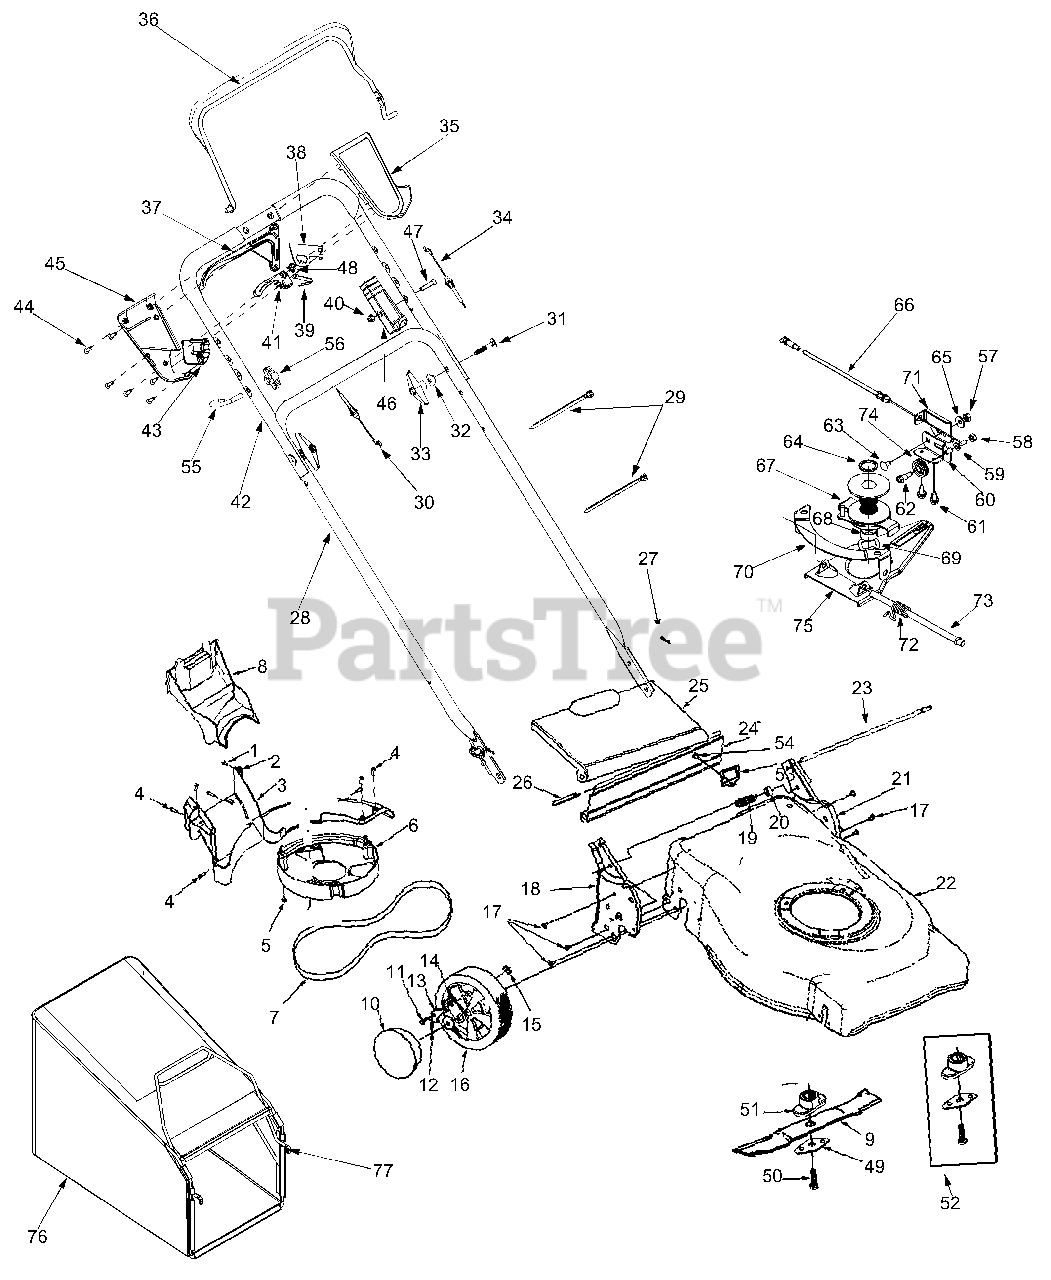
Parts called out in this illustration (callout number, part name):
1	Screw Mach. B Tapp
2	U-Nut
4	Screw HL 12-24
5	Tap Screw 1/4-20
6	Belt Cover
7	Belt
8	Mulch Plug
9	21" Mulching Blade w/Star
10	Hub Cap
11	Shldr. Scr.340 x .285
12	Ratchet Spring
13	Pawl R.H.
14	Ratchet Pawl Plate
15	Top Lock Weld Nut 1/4-20
16	Wheel Assembly
17	Screw AB 1/4-20
20	Spacer.385 I.D.
24	Rear Flap 17.77 Lg.
27	Cotter Pin
29	Cable Tie
30	Drive Cable
31	Cr.Hd. Bolt 5/16-18 x 2" Lg.
32	Saddle Washer.320 ID x.830 OD
34	Control Cable-49"
35	Upper Control Housing
36	Deluxe Control Handle
37	Drive Control Lever
38	6-Speed Rack Cable Bracket
39	Shift Lever Spring
40	Top Lock Nut
41	6-Speed Shift Lever
43	Cable Mounting Cover
44	C-Sunk Tap Screw #10-x.75 Lg
45	Lower Control Housing
46	Control Housing
47	Oval C Sunk Screw
48	3 Tooth Insert Rack Gear
49	Blade Bell Support
50	Hex Bolt 3/8-24 x 2.5 Lg.
51	Blade Adapter
52	Blade Adapter Kit w/Star
55	Rope Guide
56	Handle Knob
57	Hex Nut 1/4-20
58	Hex Nut 1/4-28
59	Lock Washer 1/4
62	Screw 1/4-20 x.375
63	Screw 1/4-20 x.625
64	Sleeve Spacer 88ID x 1.13 x.12
65	Bell Washer.265 x.75 x.062
66	6-Speed Cable - 53"
67	Pulley Assembly Complete
68	Sleeve Spacer 88 ID x 1.00 x.48
69	Wave Washer 1.38 OD x.88 ID.029
73	Pivot Shaft 3/8OD x 7.75 LG
74	Cable Roller
